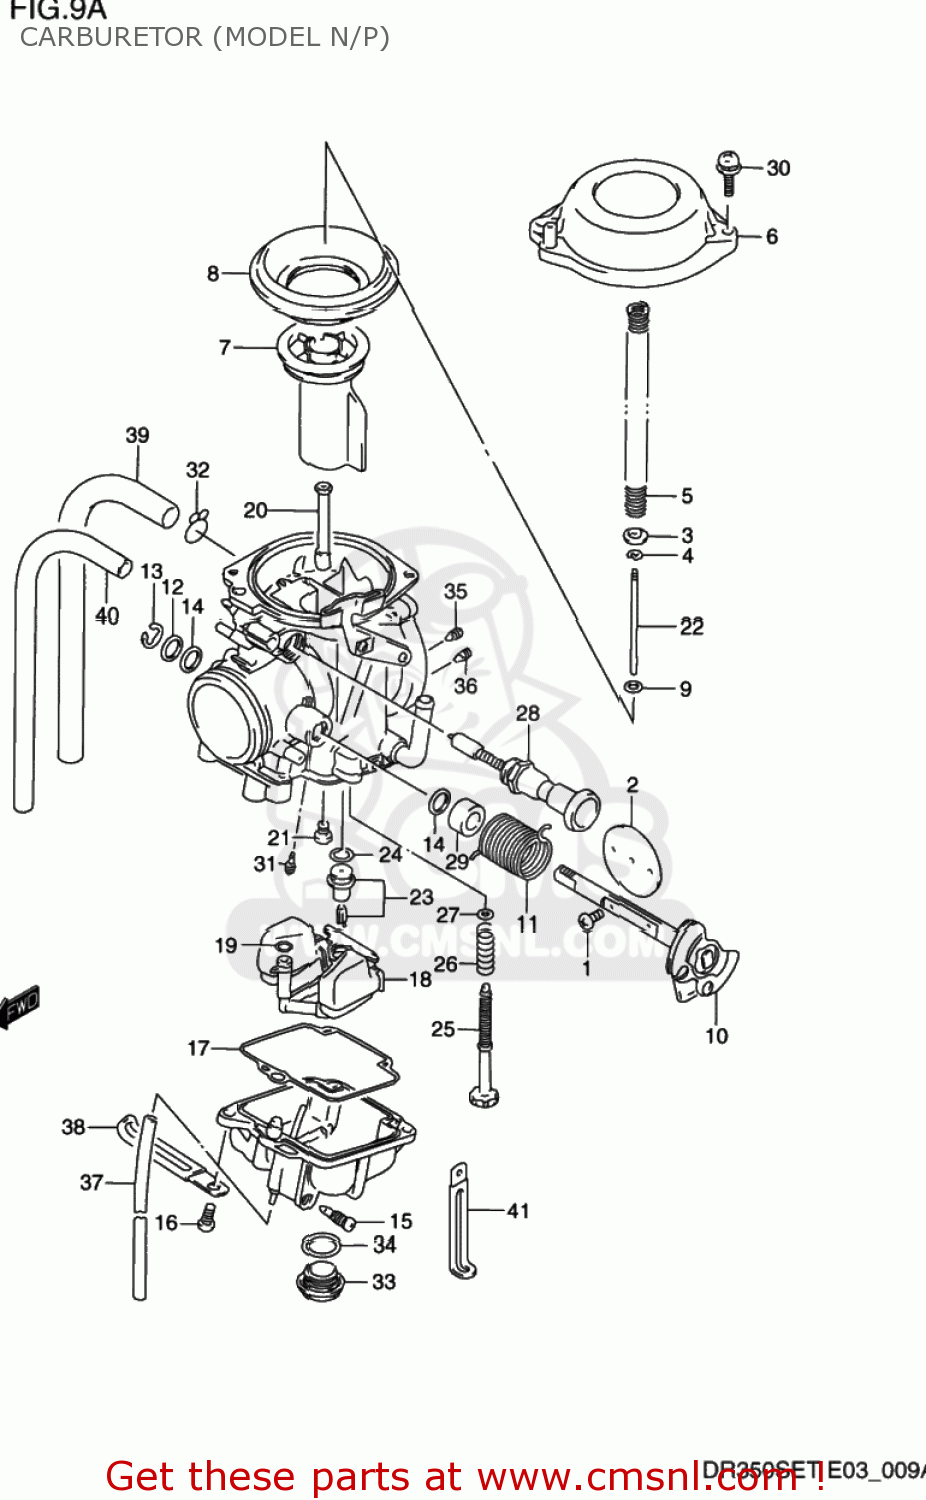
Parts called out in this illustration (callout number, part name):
1	SCREW
2	VALVE,THROTTLE (115)
3	RING
4	E RING
5	SPRING
6	COVER,DIAPHRAGM
7	VALVE PISTON
8	DIAPHRAGM
9	RING
10	SHAFT ASSEMBLY
11	SPRING
12	GASKET,THROTTLE SHAFT (NAS)
13	E RING
14	SEAL
15	SCREW,DRAIN
16	SCREW
17	GASKET,FLOAT CHAMBER (NAS)
18	FLOAT ASSY
19	O RING
20	JET,NEEDLE (O-6)
21	JET,MAIN(135)
22	NEEDLE,JET
23	VALVE ASSEMBLY,NEEDLE
24	O-RING,NEEDLE VALVE
25	SCREW,ADJUSTER
26	SPRING
27	WASHER
28	PLUNGER ASSEMBLY
29	RING
30	SCREW
31	JET,PILOT(37.5)
32	CLIP
33	SCREW,GUIDE
34	O RING,DRAIN PLUG
35	JET,AIR(1.3)
36	JET,AIR(0.6)
37	HOSE
38	CLIP
39	HOSE
40	HOSE
41	CLAMP L:35
